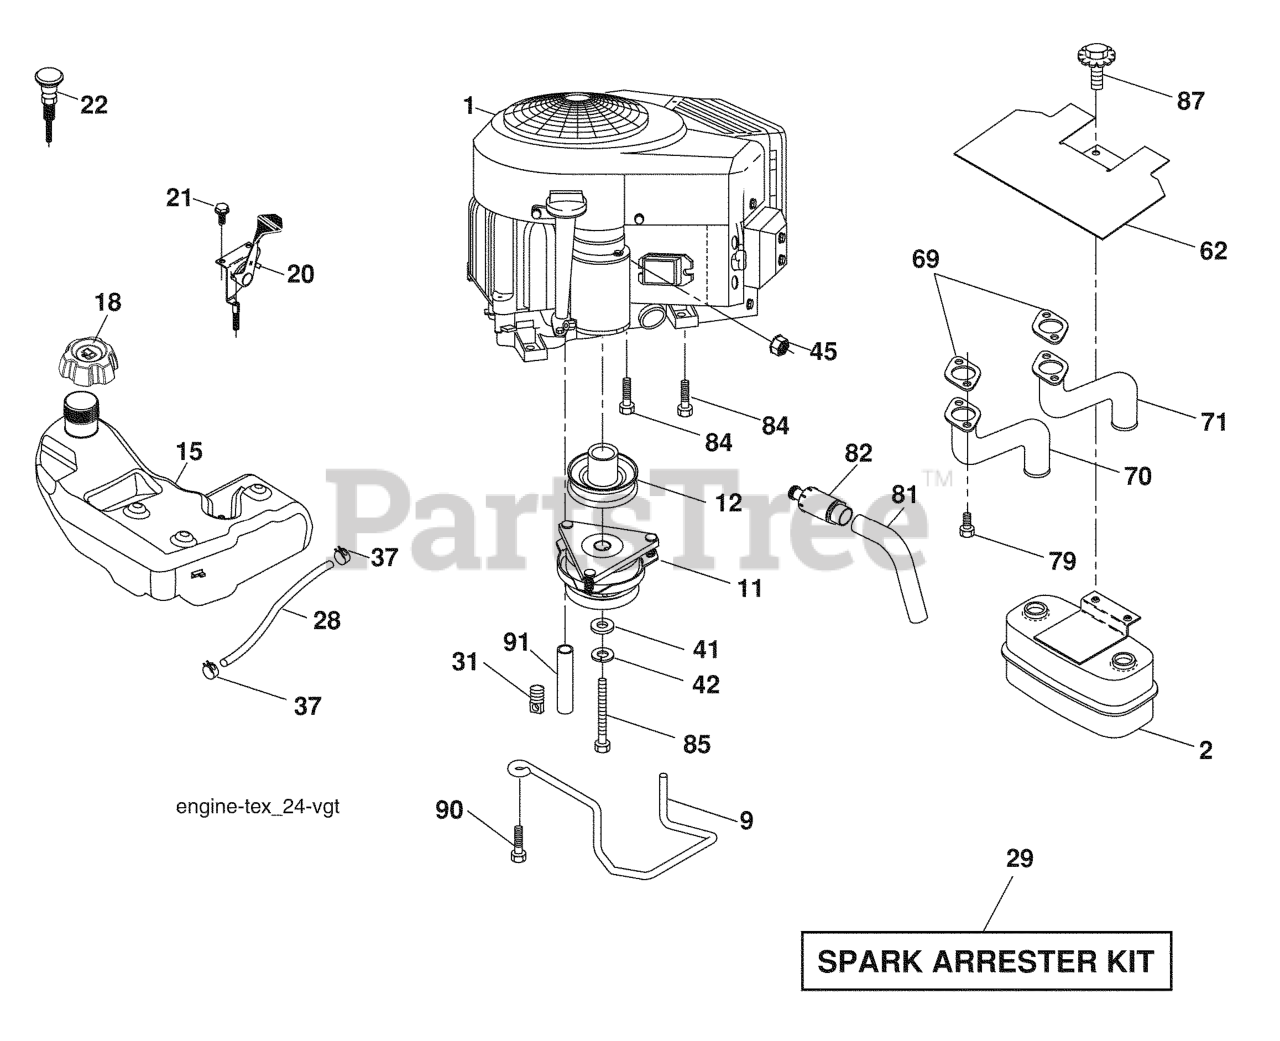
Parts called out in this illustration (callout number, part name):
2	MUFFLER.TWIN.CYL.LOW.TONE
9	KEEPER.BELT.ENGINE.4.2
11	CLUTCH MZ ZTR GT.48/54"1.125"
12	PULLEY ENGINE
15	TANK.FUEL.4GAL
18	CAP.FUEL.TANK.3"GREY
20	THROTTLE CABLE
21	SCREW.#10 X 0.750.BOS
22	CONTROL.CHOKE.ERGO.PUSH-IN.BLA
28	LINE.FUEL.64"REAR.EMIS
29	KIT.SPARK ARRESTOR 794945 B&S
37	HOSE CLAMP
42	LOCKWASHER
45	NUT
62	RP SHIELD HEAT MUFFLER
69	GASKET.MUFFLER
70	RP.EXHAUST.TUBE.LH.BS/TWIN
71	EXHAUST.TUBE.RH.BS/TWIN
79	SCREW.SOCKET.HEAD.5/16-18
81	TUBE, DRAIN OIL ASM.
82	PLUG DRAIN OIL EASY
84	SCREW.3/8-16
85	BOLT HEX 7/16-20 X 3.75 GR. 5
87	BOLT.5/16-18UNCX1.W/SEMS.BLK
90	SCREW 3/8-16X1
91	BUSHING.1.375OD
